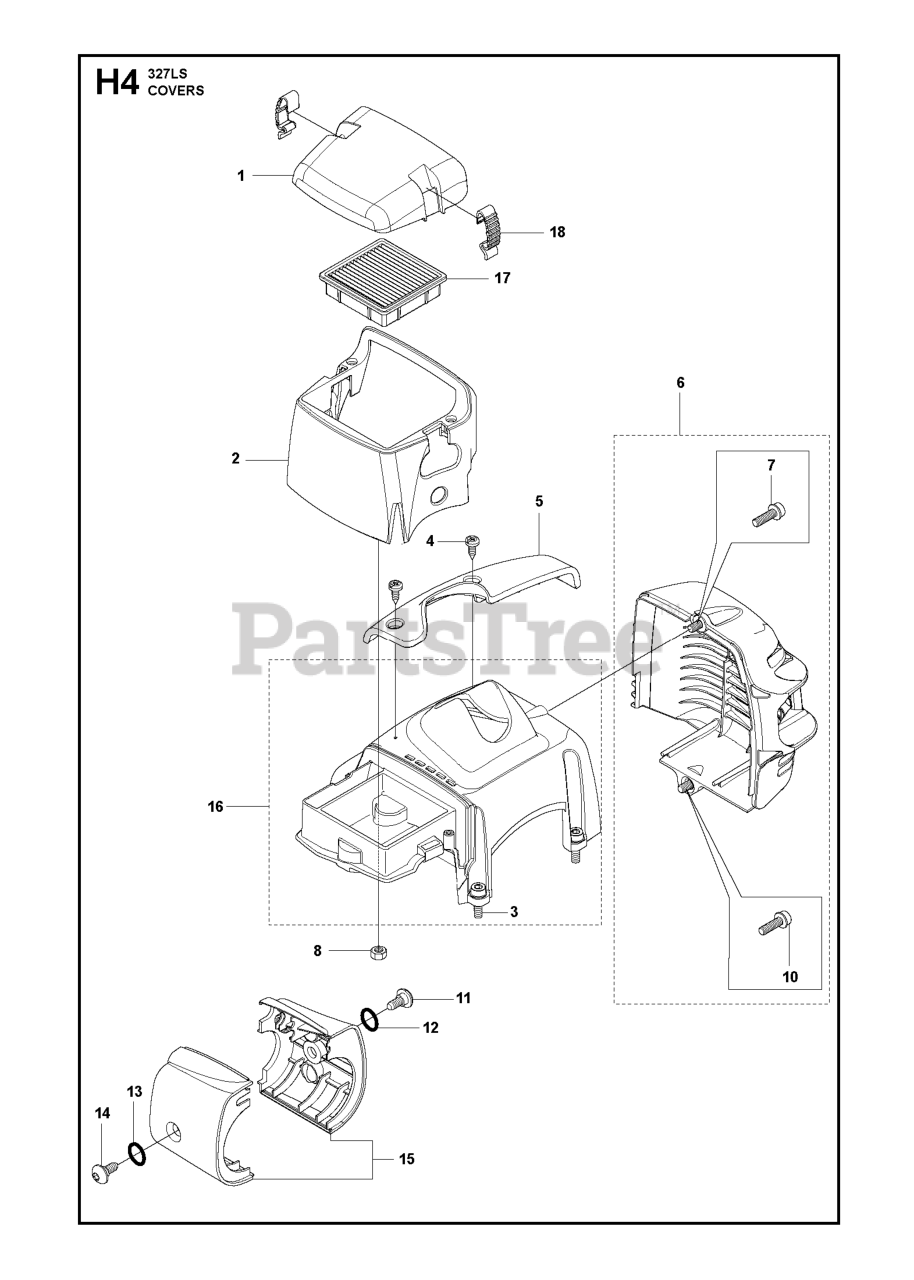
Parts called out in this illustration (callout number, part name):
1	FILTER COVER
3	SCREW IHSCFMO
5	ARM PROTECTION
6	HEAT PROTECTOR
7	SCREW IHSCFTO
10	SCREW IHSCFMO
11	SCREW MT5X11
12	O-RING 8X1.6
13	O-RING 8X1.6
14	SCREW MT5X11
16	CYLINDER COVER ASSY
